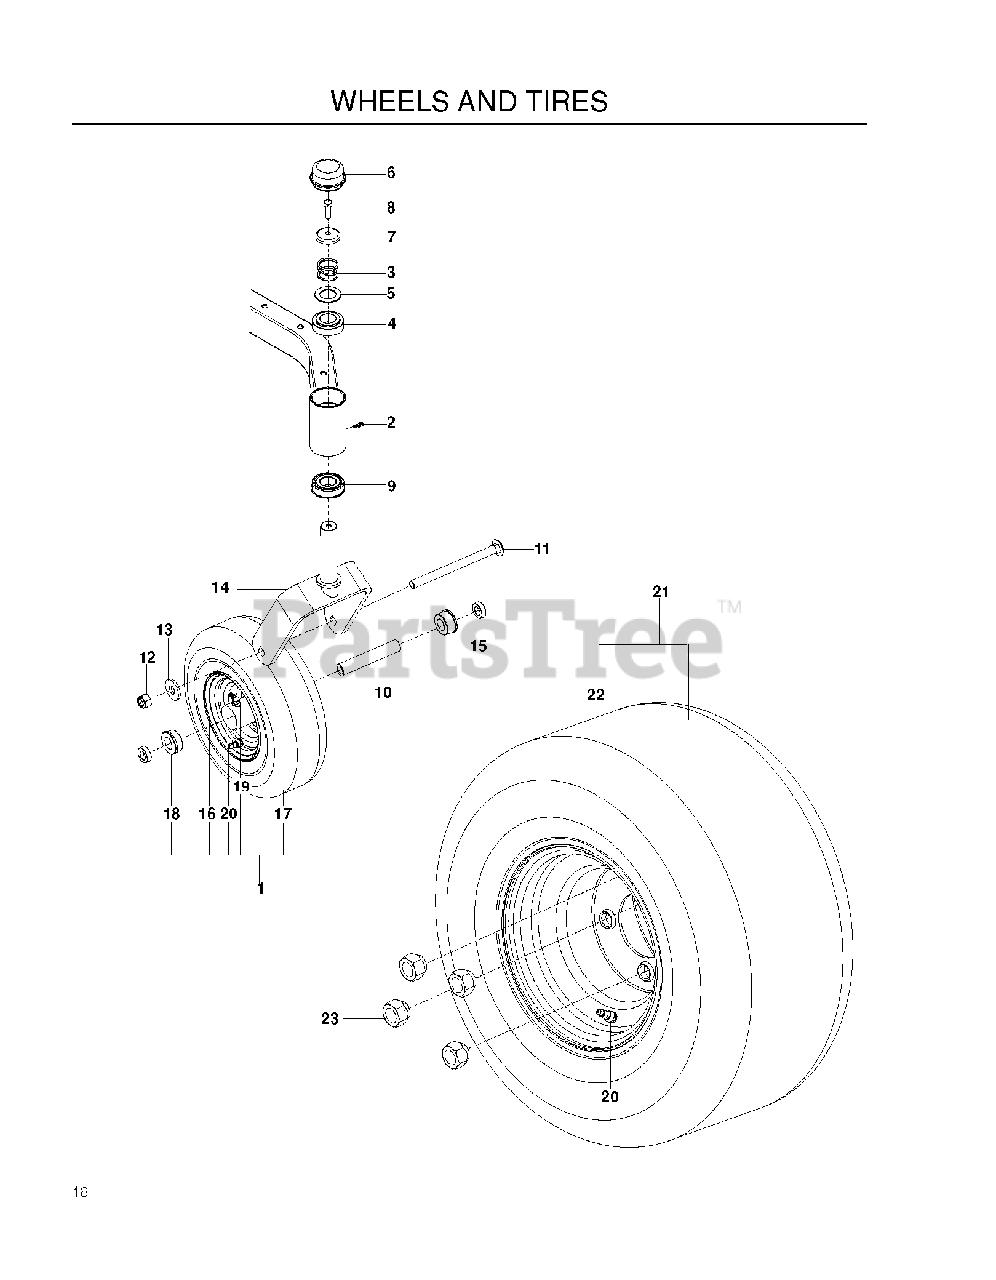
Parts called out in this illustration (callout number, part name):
1	TIRE.CASTER.ASSEM.11X4-5.GR
2	ZERK, 3/16, DRIVE IN
3	SPRING, CASTER
4	BUSHING, CASTER
5	WASHER, 1.025 ID X 1.64
6	GREASE CAP
7	CASTER.PLUG
8	5/16-18X1 HHB G5W/NY
9	BEARING FLANGED
11	RHSNB 1/2-13 X 6.50 GR2 ZD
12	NUT 1/2-13 HEX CNTRLK GR 5 ZD
13	WASH USS FLAT 1/2
14	YOKE.CASTER.BLACK
15	SPACER, 5/16"
17	TIRE.11"X4"-5.4PLY.SMOOTH.KEND
18	BUSHING, WHEEL, 3/4"
19	ZERK
20	VALVE STEM TR-412
21	TIRE ASM 18 X 8.5-8
22	RIM.8X7.SILVER.ZTR
23	LUG NUT 1/2F
